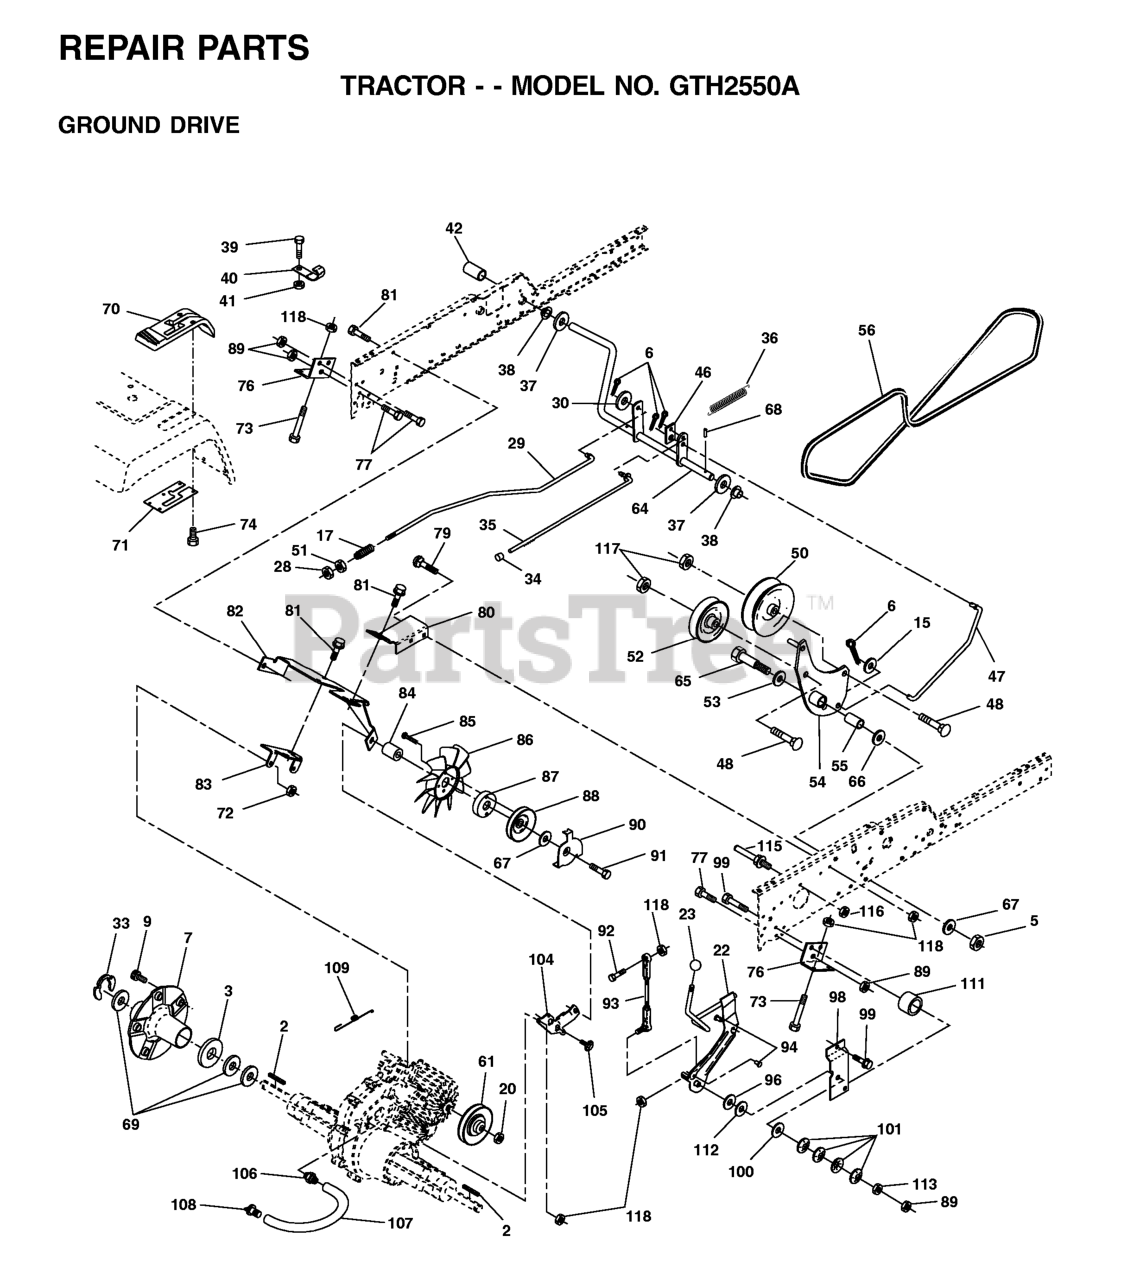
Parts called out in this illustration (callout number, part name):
2	KEY 1/4 X 2.5
6	COTTER PIN
7	HUB ASMBLY
15	WASHER
17	SPRING.ROD.BRAKE
20	NUT.HEX.1/2-20
22	SHAFT ARM ASM
23	KNOB.DELUXE.(PISTOL.GRIP).BLAC
28	NUT
30	WASHER
33	E RING HYT
34	PLUNGER CAP
35	PARKING BRAKE ROD
36	SPRING DRIVE GROUND
39	Screw, Fin. #10-24 x 1
40	ACTUATOR INTERLOCK SWITCH
41	Nut Centerlock 10-24 unc
42	PEDAL COVER T
46	RETAINER SPRING
47	CLUTCH ROD
48	BOLT.3/8-16X1.50
50	FLAT IDLER PULLEY
52	PULLEY.IDLER.V.
55	BEARING LT (2 2)
64	SHAFT CLUTCH/BRAKE PEDAL
67	WASHER
68	ROLL PIN STD
71	PLATE CONSOLE SHIFT
72	NUT.71038.31-18.HEX.NYLOCK
73	BOLT HEX FLGHD 5/16-18X3 GR. 5
74	SCREW.HI-LO.CONSOLE
76	BRACKET TRANSAXLE
77	BOLT
79	BOLT.CARR.5/16-18X5/8.SHORT
80	TORQUE BRACKET RH
81	SCREW 3/8-16X3/4
82	BRACKET MOUNT TORQUE/FAN
83	STRAP TORQUE MID
85	Screw #10-24 x 1-1/4
86	FAN 7" HYDRO
87	ADAPTOR.FAN.TRANSAXLE.VGTH
89	Nut, Crownlock Hex 7/16-14 unc
90	KEEPER.BELT
91	SCREW.HXWSH.3/8
92	BOLT
93	LINK ASM SHIFT
94	FASTENER.XMAS.TREE
98	SHIFT BRACKET
99	SCREW 3/8-16 X 1-1/2
101	WASHER BELLVILLE
104	BRACKET IDLER
105	SCREW CRT
106	O-RING KIT 70110
107	LINE.VENT.HYDRO-GEAR
108	CAP, VENT ASSY
109	RETURN SPRING
111	SPACER SHIFT LEVER VGTH
112	WASHER NYLON HIGH TEMP
115	KEEPER,DRIVE BELT
116	NUT LOCK HEX FLANGE 5/16-18
117	NUT LOCK FLG 3/8-16 UNC
